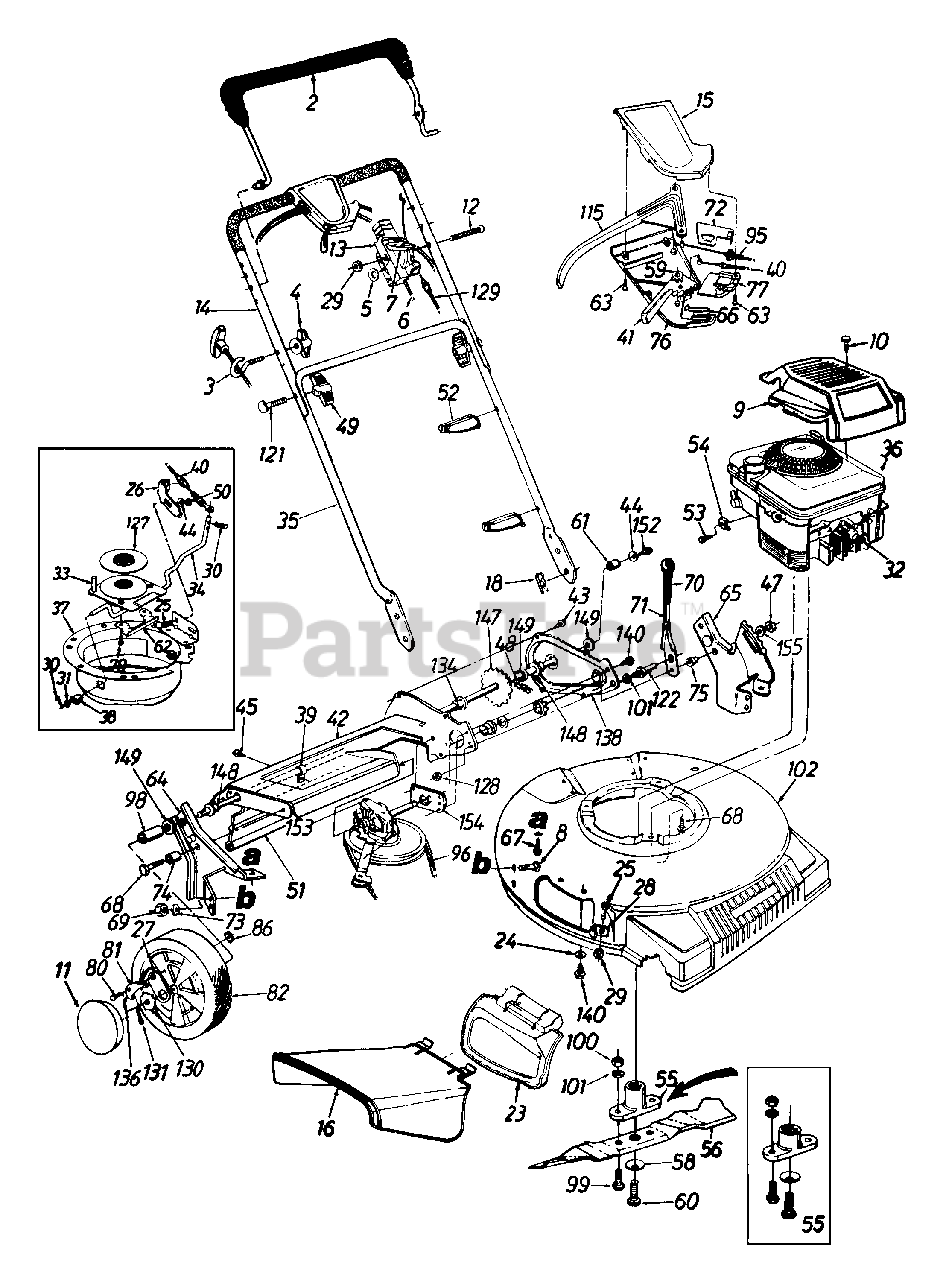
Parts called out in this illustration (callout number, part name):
2	Control Handle
3	Rope Guide
4	Handle Knob 1/4-20 Thd.
5	Curved Spring Wash..66" I.D.
6	Throttle Wire - 55" Lg.
7	Throttle Lever
8	Carriage Bolt 5/16-18 x .62" Lg.
9	Engine Shroud
10	Hi-Lo Screw #10 x 1.25" Lg.
11	Hub Cap
12	Oval C-Sunk Mach. Scr.
13	Throttle Body
15	Upper Control Housing
16	Side Chute Deflector
18	Internal Cotter Pin 5/16" Dia.
23	Mulch Plug Ass'y. Comp.
24	Bell-Wash..265" I.D. x .75" O.D.
25	Carriage Bolt 1/4-20 x .5" Lg.
30	Cotter Pin 3/32" Dia. x .75"
31	FI-Wash..328" I.D. x .68"
32	Spark Plug Insulator
33	Pulley Ass'y.
36	Engine - 5.5 H.P.
37	Housing Ass'y.
38	Flanged Bushing
40	6 Spd. Cable
41	6 Spd. Shift Lever
44	Bell-Wash. 1/4" I.D.
47	Hex Patch L-Nut 3/8-24 Thd.
48	#48 Chain .500" Pitch x 38 Links
49	Hand Knob
50	Hex L-Nut 1/4-20 Thd.
51	Rear Flap 4.8" x 17.5" Lg.
52	Cable Tie
53	Hex Wash. Hd. Scr. #10-32 x .62" Lg.
54	Casing Clamp
55	Blade Adapter Kit
56	21" Mulching Blade
58	Bell-Wash..39" I.D. x 1.14" O.D.
59	Gear Insert
60	Hex Bolt 3/8-24 x 2.5" Lg. (Gr. 8)
61	Spacer .513" i.D.
67	Hex B-Tap Scr 5/16-18
68	Hex TT-Tap Scr. 3/8-16
69	Hex Nut 5/16-18 Thd.
71	Height Adj. Lever
72	6 Spd. Rack Cable Brkt.
73	Bell-Wash 5/16" I.D
74	Spacer .383" I.D.
75	Shld. Spacer .5" Dia
76	Lower Control Housing
77	Cable Mounting Cap
80	Shld. Scr..342" Dia. x .268
81	Pawl - R H.
82	Wheel Ass'y. Comp.
86	Weld Top L-Nut 1/4-20 Thd.
95	S.P. Cable
96	"V"-Belt
98	Sleeve .526" I. D
99	Hex Bolt 3/8-24 x 1.0" Lg.
100	Hex Nut 3/8-24 Thd.
101	L-Wash. 3/8" I.D.
121	Curved Hd Bolt 5/16-18 x 2" Lg.
122	Shld. Pin 1.43" Lg
128	Hex Jam Nut 3/8-24 Thd.
129	Control Cable - 39"
130	Ratchet Wheel 1.62" O.D.
131	Cotter Pin 1/8" Dia. x 1"
134	Hex Flange Bearing
136	Spring - Nylon
147	Rear Shaft Ass'y. 21.44" Lg.
148	Hex Flange Brg..506" I.D.
149	Fl-Wash. 531" I.D. x.930"
152	Hex Bolt 1/4-20 x .62" Lg. (Gr. 5)
153	Transmission Comp.
155	Fl-Wash. 385" I.D. x .87" O.D.
